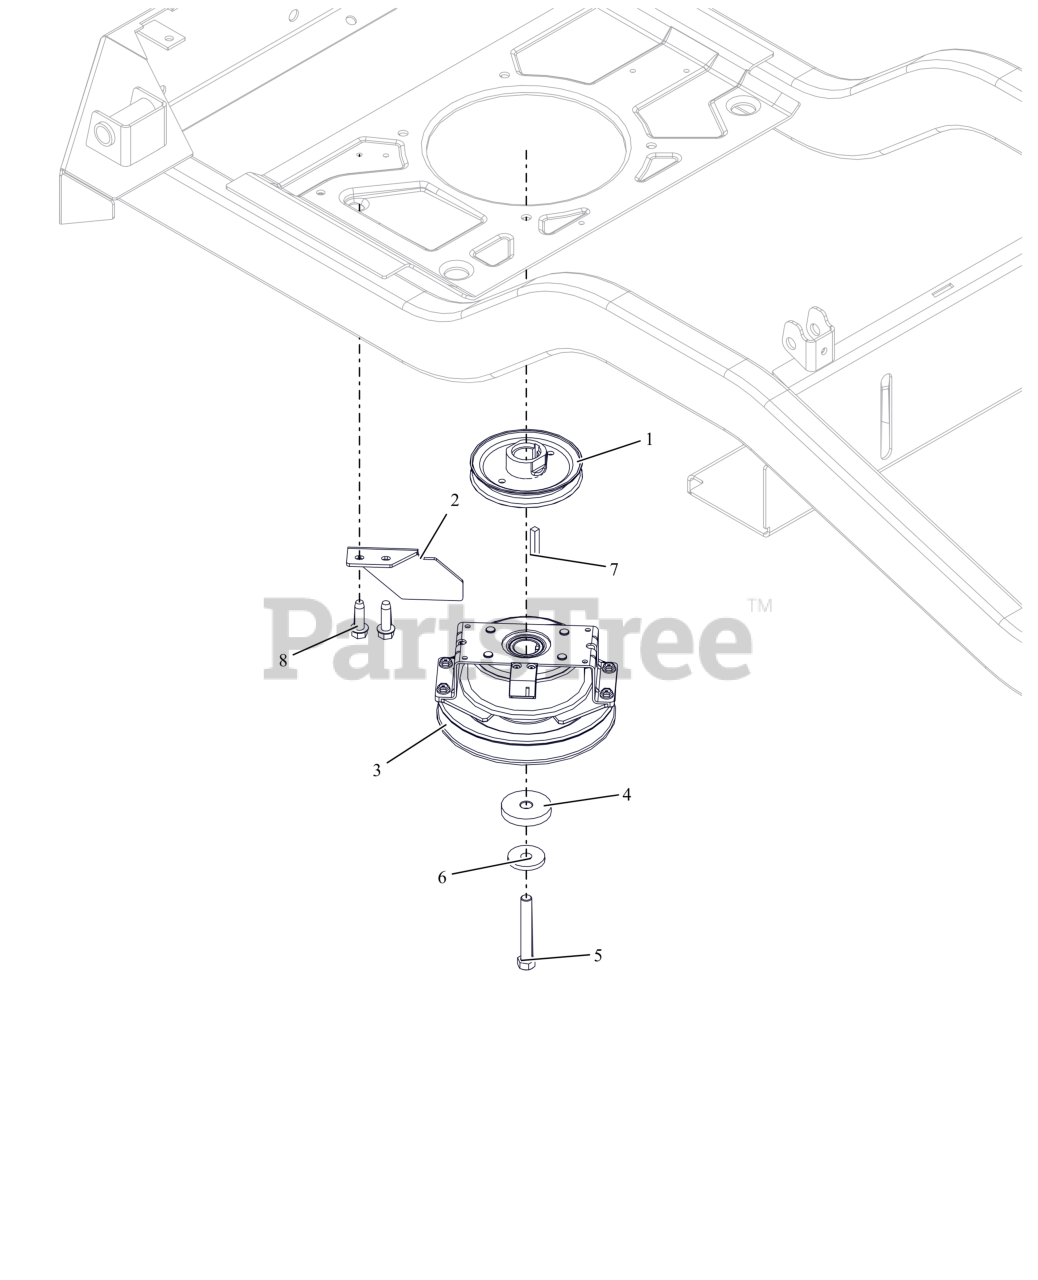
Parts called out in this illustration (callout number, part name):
1	WLDMT,PULLEY-4.50ODX1.003
2	BRKT, CLUTCH STOP HD
3	CLUTCH, OGURA DBL SPRG
4	SPACER, .474/.459X2.00X.350
5	BLT, HEX .44-20X3.00 G8 ZCC NT
6	WASHER, 7/16" SPRING DISK
7	KEY-SQ .25 X 1.25 X .25 SAE
8	SCR,TAP .375-16X1.25HWH TR ZCC
